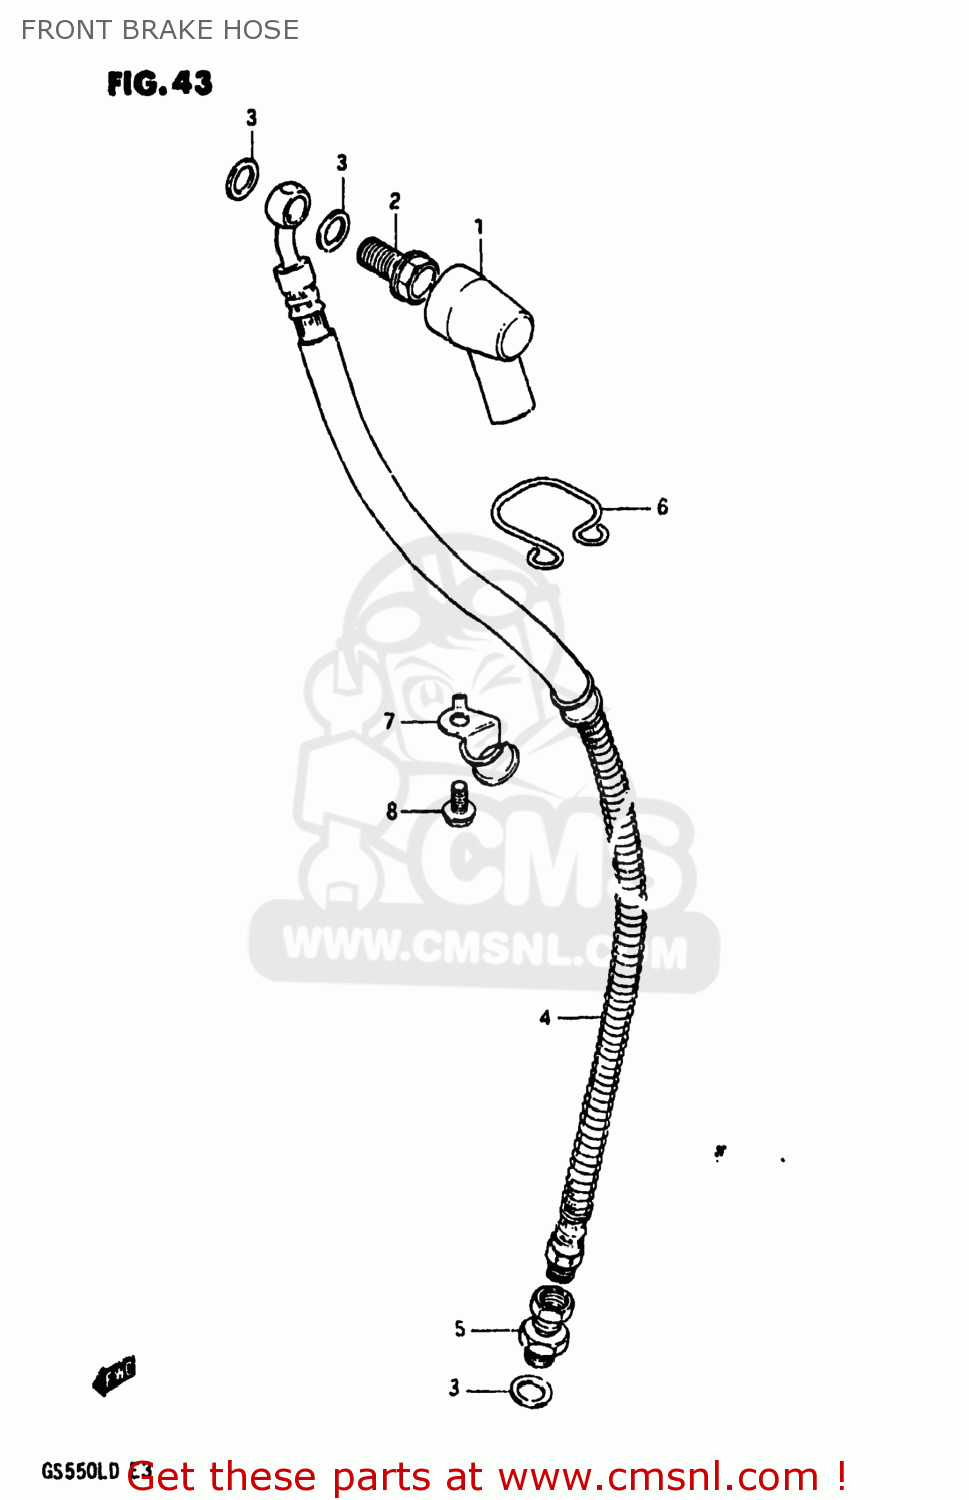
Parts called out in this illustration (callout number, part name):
1	BOOT,MASTER CYLINDER
2	BOLT UNION
3	WASHER
4	HOSE,FRONT BRAKE
5	ADAPTER,BRAKE HOSE
6	GUIDE,CABLE/HARNESS
7	GUIDE,BRAKE HOSE NO.3
8	BOLT
